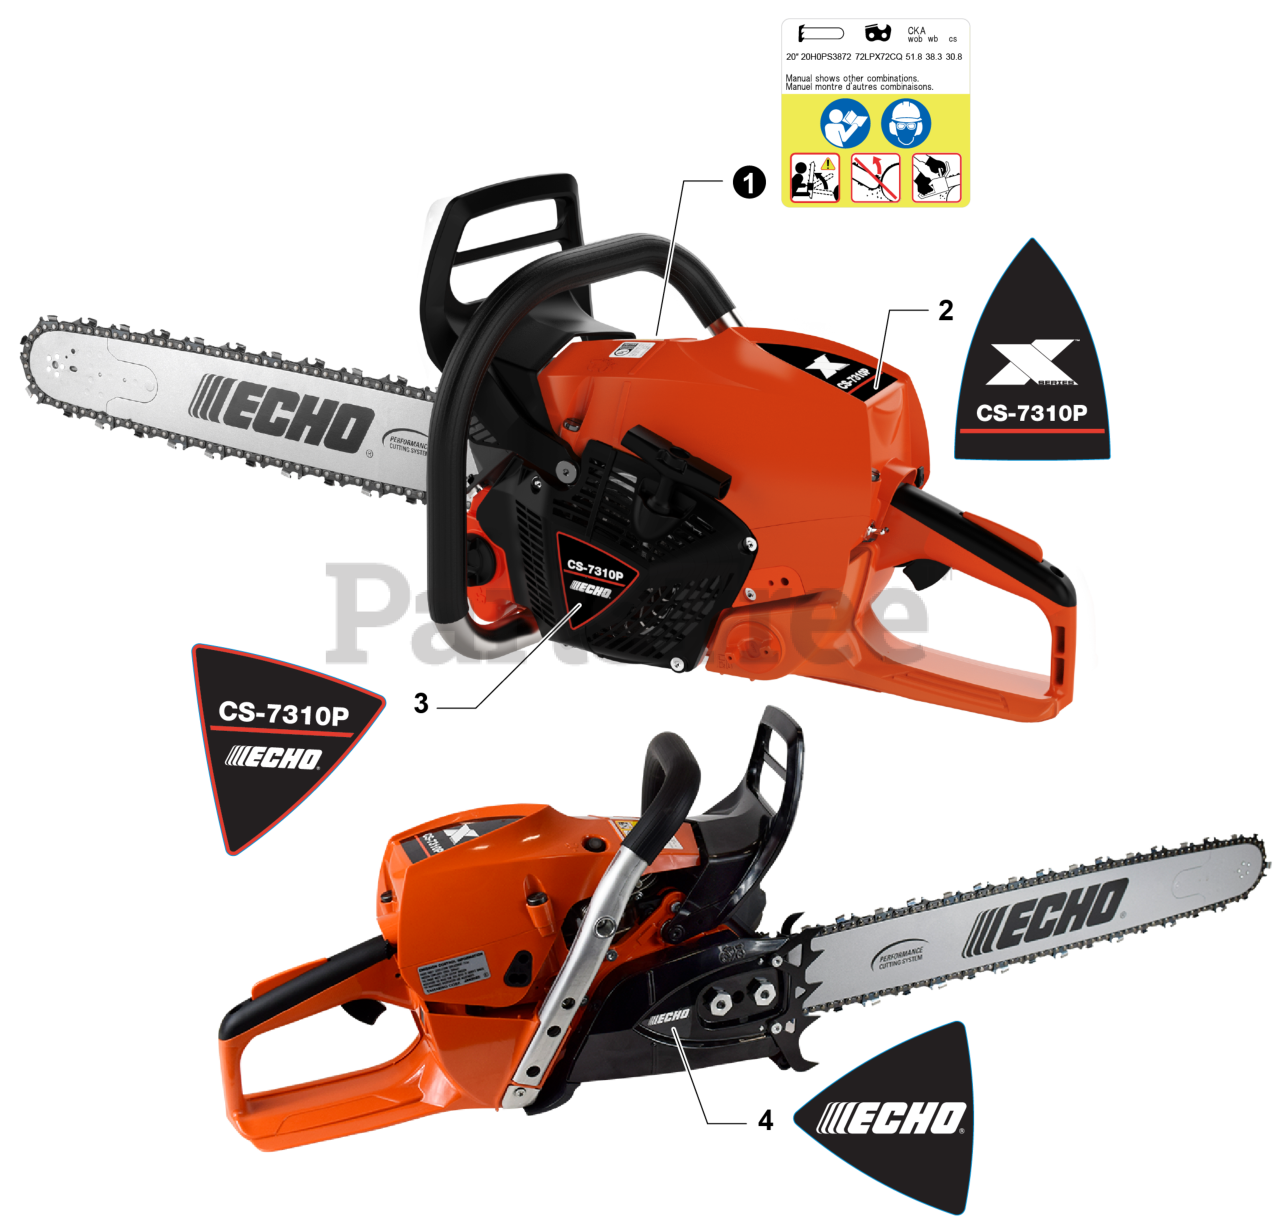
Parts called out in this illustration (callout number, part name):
1	LABEL - CAUTION - ISO
2	LABEL - MODEL CS-7310P
3	LABEL - RECOIL STARTER
4	LABEL - ECHO
